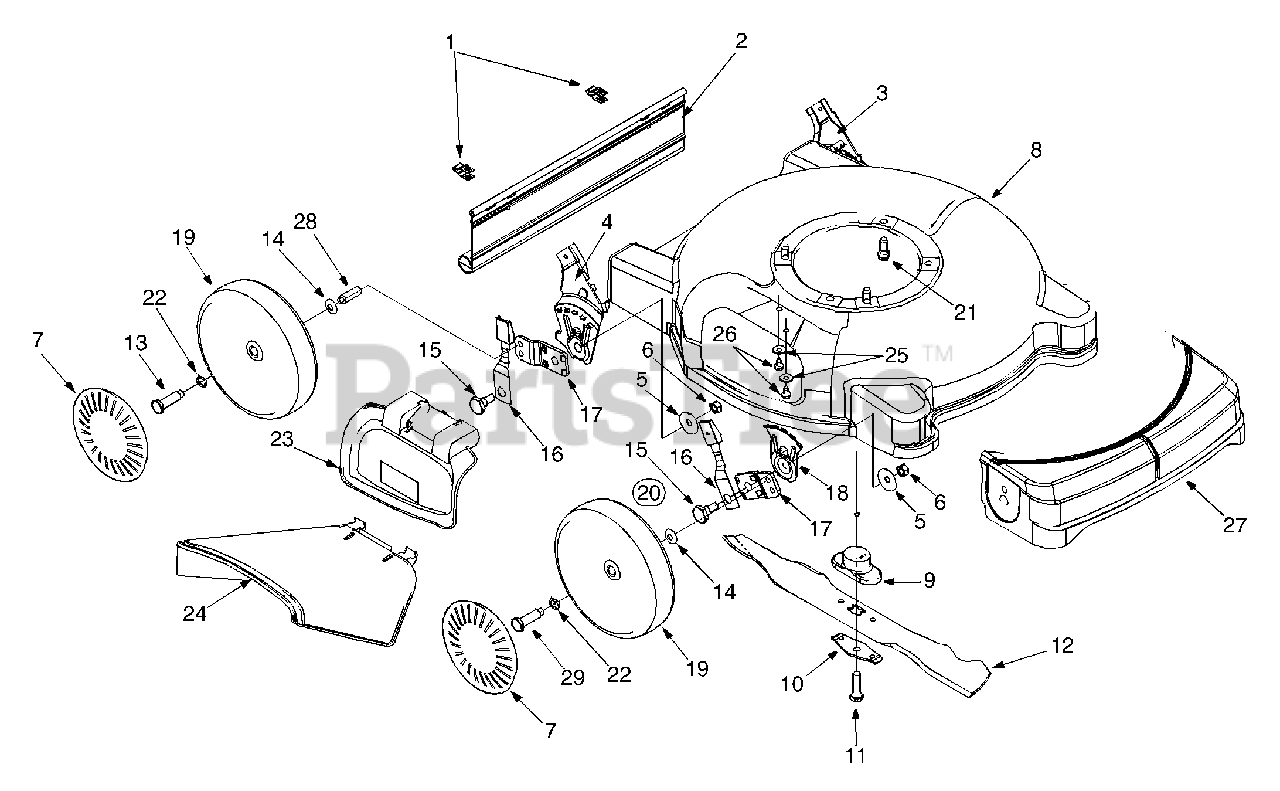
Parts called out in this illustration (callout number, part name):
1	Hinge Clip
2	Rear Flap
5	Bell Washer .39" ID x 1.38"
6	Hex Nut 3/8-16 Thd.
7	Hub Cap: Grey
10	Blade Bell Support
11	Hex Bolt 7/16-20 x 1.5"
12	20" Mulch Blade
13	Axle Bolt
14	Bell Washer .400" ID x .88"
15	Shoulder Bolt
16	Spring Lever Ass'y w/Knob
18	Height Adj. Plate
19	Wheel Assembly
20	Height Adj. Ass'y. Comp. R.F.
21	Hex Lock Wash. Hd. Screw 3/8-16 x 1.0" Lg.
22	Wave Washer
23	Mulching Plug
24	Chute Deflector
26	Hex Wash. Hd. TT Screw 1/4-20 x .5" Lg.
27	Cover: Front End
28	Spacer
